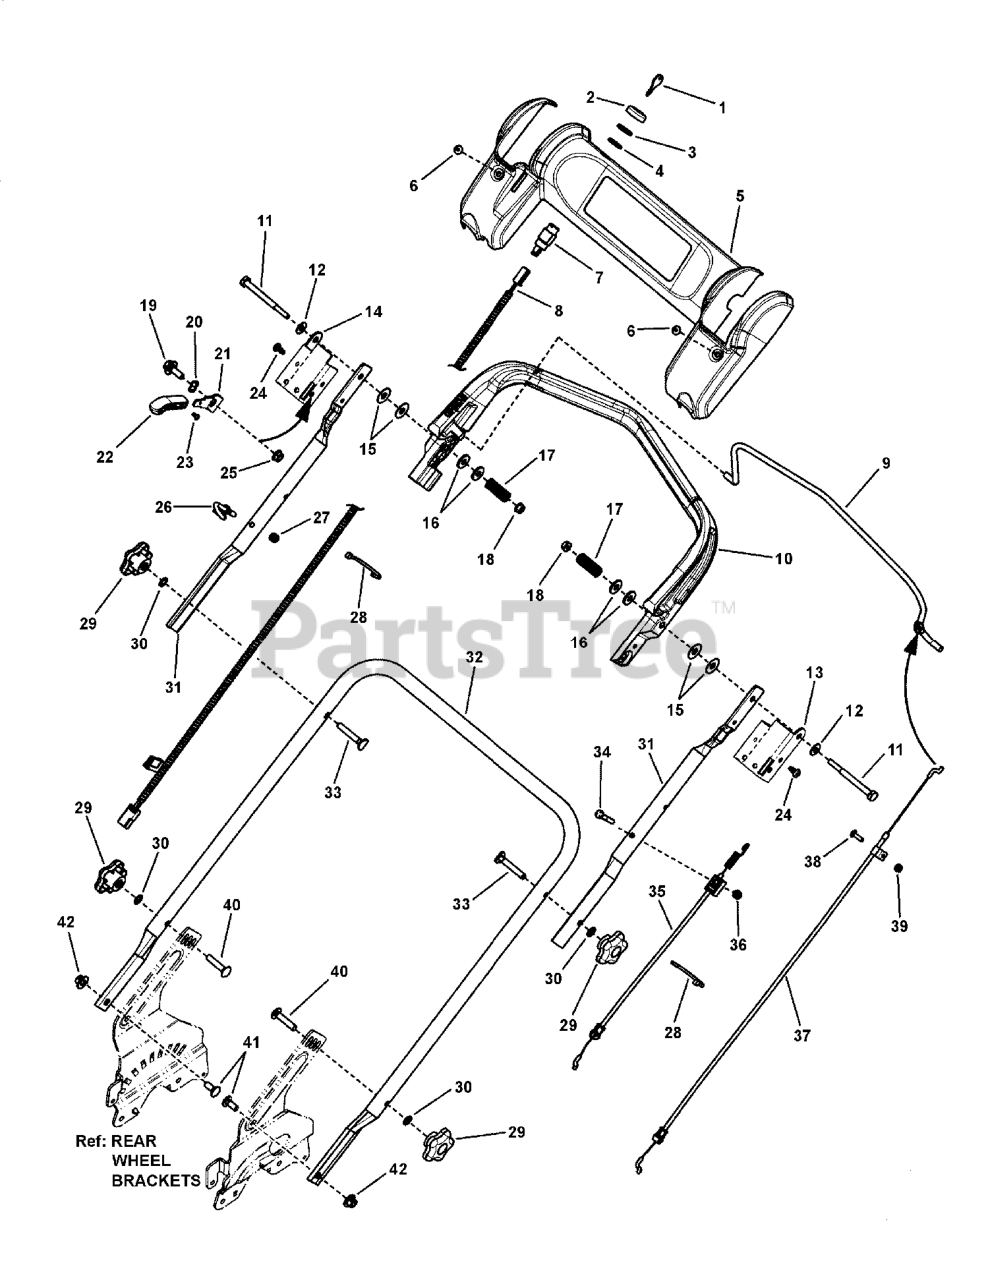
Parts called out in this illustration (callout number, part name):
1	IGN KEY, PR
2	BEZEL, GREEN
3	HN, 5/8-32 (IGN SWITCH)
4	SPACER, .65X.88X.10
5	PANEL, UPPER HANDLE, DEERE
6	RIVET, POP.250D .6L AL,STL STEM-BLACK
7	SWITCH, E/S (START/RUN)
8	HARNESS, WIRING, EL START
9	BAIL, PIVOTING HANDLE - 21" JD WBM
10	HANDLE, PIVOTING - DEERE WALK
11	BOLT, SHOULDER, 5/16 X 2.500, YZ
12	SHIM WASHER, 5/16 I.D.
13	BRACKET, LH, ROTATION LIMIT
14	BRACKET, RH, ROTATION LIMIT
15	WASHER, FLAT, 1" OD X .387 ID
16	FW, .33X.88X.09
17	SPRING, COMPRESSION
18	NUT, HEX FLANGE, 1/4-20, ESNA, YZ
19	IDLER PIVOT BOLT (5/16-18 thread)
20	WASHER, .531 X .781 3-WAVE
21	HANDLE, LOCK
22	THROTTLE CONTROL LEVER
23	RIVET, PLASTIC SNAP
24	TORX ST, 1/4-20 X .550
25	FLN, 5/16-18 YZ
26	GUIDE, ROPE (1/4-20 thread)
27	HN, 1/4C NYL RNG
28	WIRE TIE, 11 INCH STD BLK NYLON
29	KNOB, HANDLE, 5 PRONG
30	ITLW, 5/16
31	HANDLE, UPPER, STRAIGHT, EASY LINE
32	HANDLE, LOWER 21" RD, JD
33	CHSNB, 5/16-18 X 2 GR2
34	HHCS, 1/4CX1-3/4
35	CABLE, DRIVE, VS, FWD, JD
36	HCLN, 1/4-20
37	CABLE, BAIL, 2010 WBM
38	RHSNB,10-24X3/4,YZ
39	HLN, 10-24 UNC-2B W/NYLON INSERT
40	BOLT, RD HD SH SQ NK 5/16-18X1.500 G5 YZ
41	RHSSNB, 5/16-18 X 3/4 GR5 YZ
42	LHCLN, 5/16-18- BLACK
